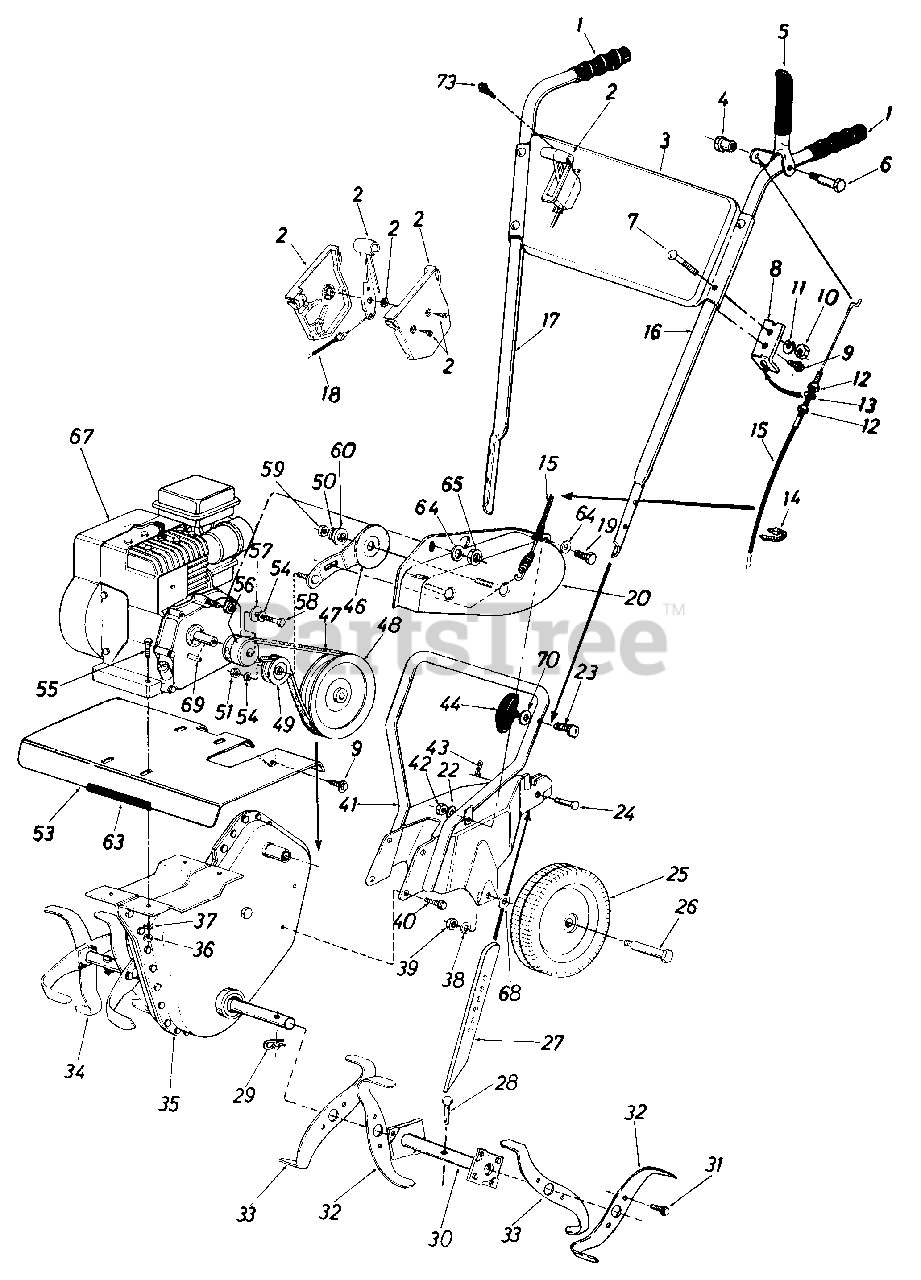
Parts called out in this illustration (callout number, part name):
2	Throttle Control Box Ass'y.
3	Handle Panel
4	Shoulder Nut
5	Clutch Grip Ass'y.
6	Shoulder Bolt 3/8" x 1.16"
7	Carriage Bolt 5/16-18 x 1.5" Lg.
8	Cable Support Bracket
9	Hex Wash. Hd. Self-Tap Scr. 1/4-20 x .50" Lg.
10	Hex Nut 5/16-18 Thd.
11	L-Wash. 5/16" I.D.
12	Hex Jam Nut 5/16-24 Thd.
13	L-Wash. 5/16" I.D.
14	Cable Tie
15	Clutch Control Cable
19	Hex Bolt 1/4-20 x .75" Lg.
20	Belt Cover Ass'y.
22	L-Wash. 1/4" I.D.
23	Curved Hd. Bolt 5/16-18 x 1.75" Lg.
24	Clevis Pin
25	Wheel Ass'y. Comp. Plastic
26	Shoulder Bolt
29	Hairpin Cotter
36	Hex Nut 5/16-18 Thd.
37	L-Wash. 5/16" I.D.
38	L-Wash. 3/8" I.D.
39	Hex Cent. L-Nut 3/8-16 Thd.
40	Hex Wash. Hd. Self-Tap Scr. 5/16-18 x .50" Lg.
43	Internal Cotter Pin
44	Hand Knob
46	Idler Arm Ass'y.
47	Belt
48	Chain Case Pulley 51/2" x 1/2"
49	Fl-ldler 2"
50	L-Wash. 5/16" I.D.
51	Hex Nut 3/8-24 Thd.
55	Hex Bolt 5/16-18 x 1.5" Lg.
56	Engine Pulley 3/8" V
57	Fl-Wash. .385" I.D. x 1" O.D.
58	Hex Bolt 3/8-24 x 1" Lg.
59	Hex Nut 5/16-18 Thd.
60	Shld. Spacer .50" Dia.
63	Trim Strip 41/2"
64	Fl-Wash. .281" I.D. x .5" O.D.
65	Hex Cent. L-Nut 1/4-20 Thd.
67	Engine
68	Bell-Wash.
69	Square Key 3/16" x 3/4" Lg.
70	Bell-Wash.
73	Self-Tap Screw #10 x .5" Lg.
